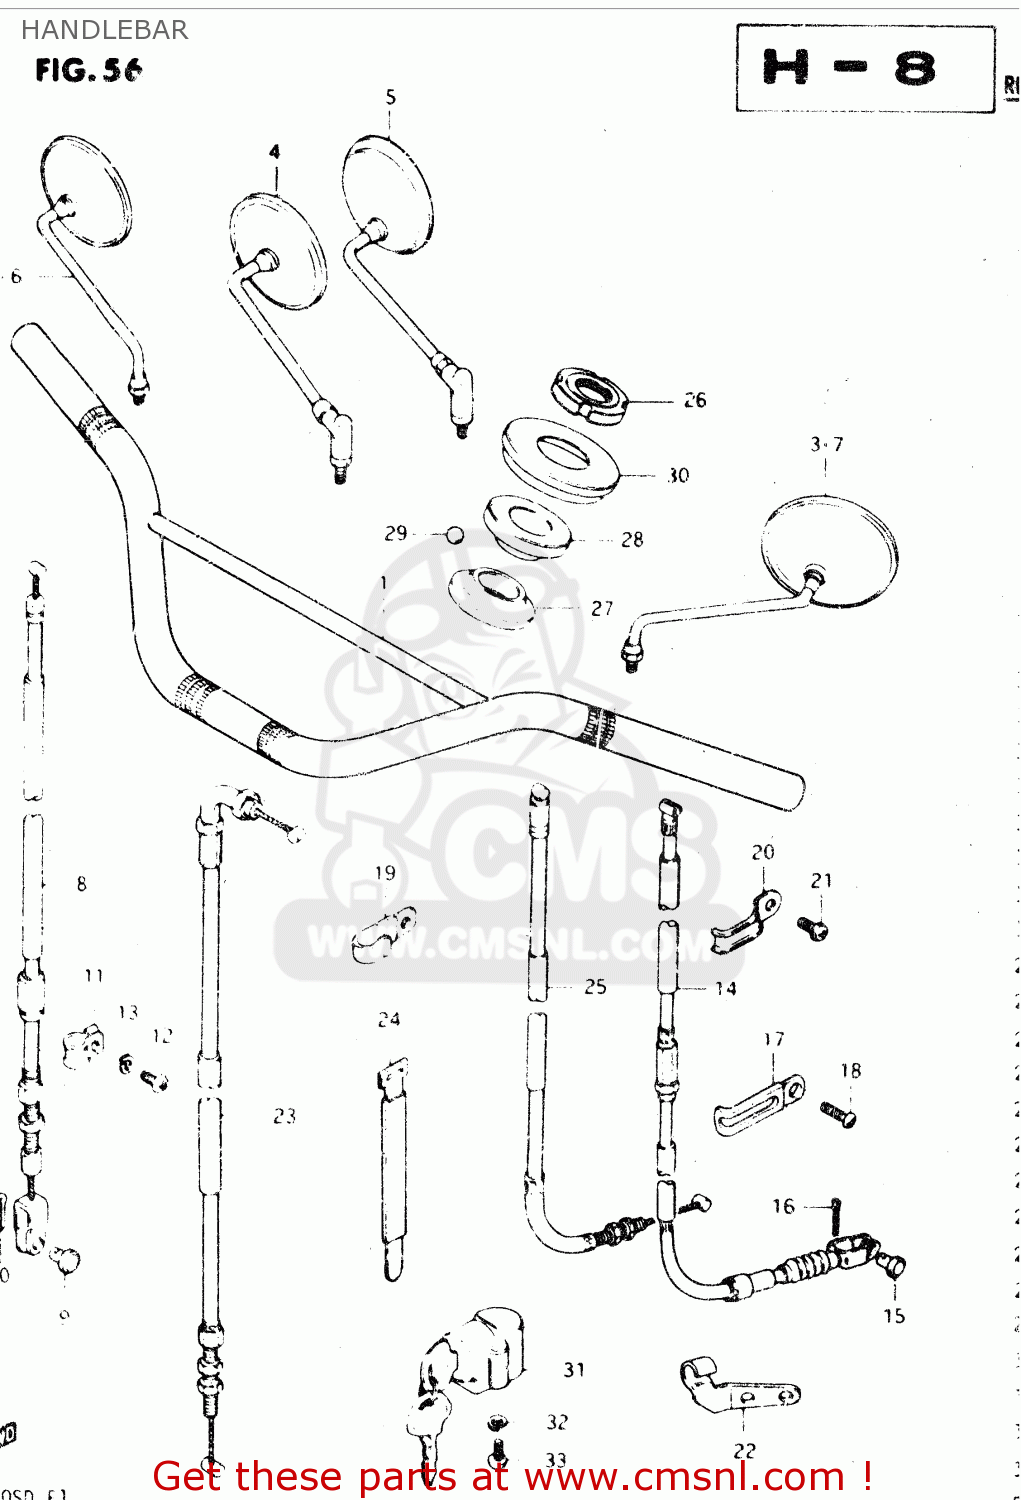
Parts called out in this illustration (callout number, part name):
1	HANDLEBAR
2	MIRROR ASSEMBLY,RIGHT
3	MIRROR ASSEMBLY,LEFT
4	MIRROR ASSY,RH
5	MIRROR ASSY,RH
6	MIRROR ASSY,RH
7	MIRROR ASSY,LH
8	CABLE ASSY,FR BRAKE
9	PIN(L:17.5)
10	PIN
11	CLAMP,FR BRAKE CABLE
12	SCREW
13	LOCK WASHER
14	CABLE ASSEMBLY,CLUTCH
15	PIN(L:13)
16	PIN
17	CLAMP
18	SCREW 6X12
19	CLAMP
20	CLAMP
21	SCREW
22	STOPPER,CLUTCH CABLE
23	CABLE ASSY,THROTTLE NO.1
24	CLAMP(L:250)
25	CABLE ASSEMBLY,DECOMPRESSION
26	NUT,STEERING STEM
27	RACE,STEERING,INNER,UPPER
28	RACE,STEERING,OUTER,UPPER
29	BALL
30	SEAL,STEERING UPR DUST
31	LOCK ASSY,STEERING
32	LOCK WASHER
33	SCREW
